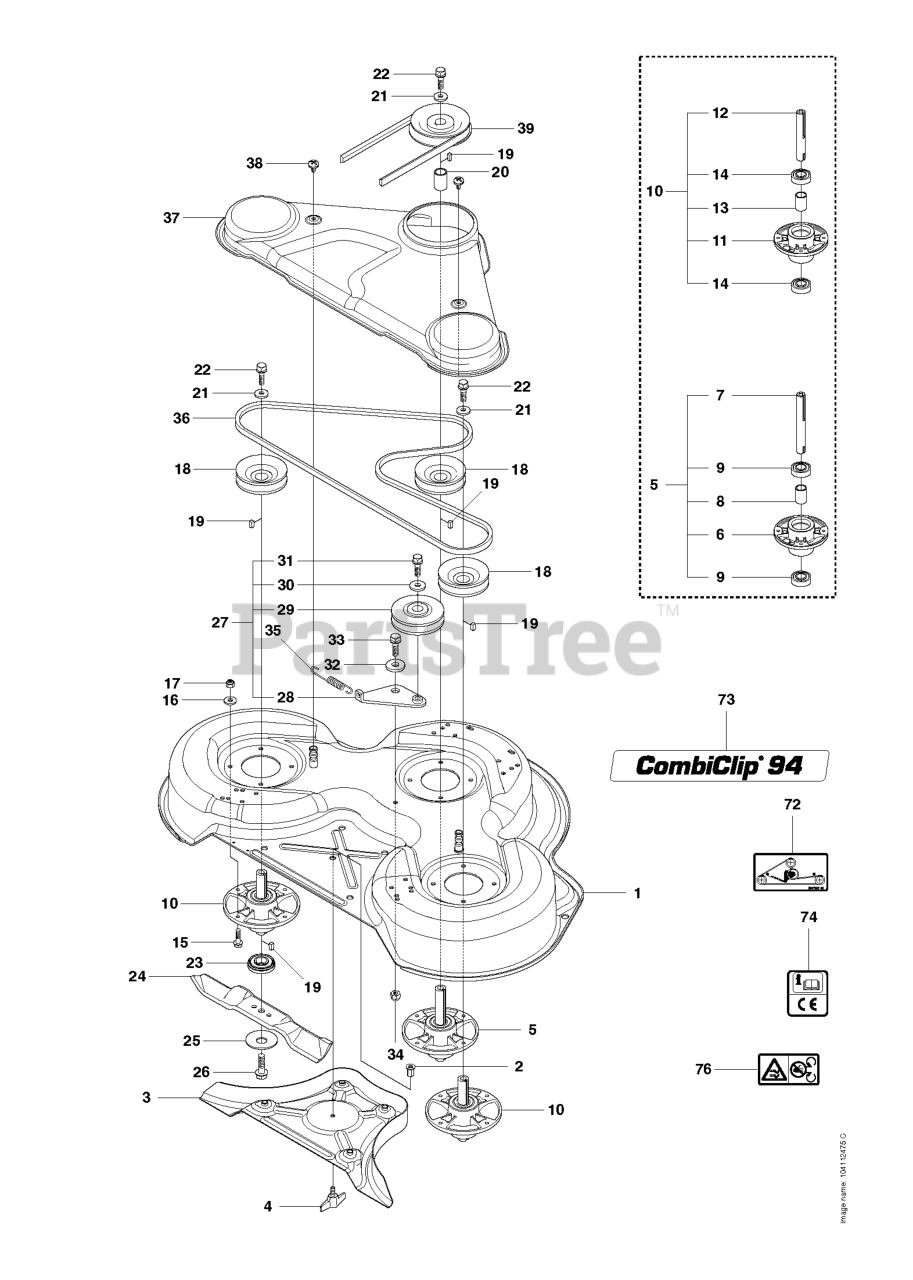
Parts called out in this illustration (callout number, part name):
1	CUTTING DECK W/PLUG GREY RIDER
3	PLUG C93 & C94
5	SPINDLE ASSY
6	BEARING HOUSING
10	RP SPINDLE ASSY
11	BEARING HOUSING
14	BALL BEARING
16	WASHER BRB 8.4X17
17	LOCKNUT M8
25	WASHER
27	BELT TENSIONER ASSY
28	BELT TENSIONING ARM
32	WASHER
34	LOCKNUT M8
37	BELT COVER C93 & C94 GREY
